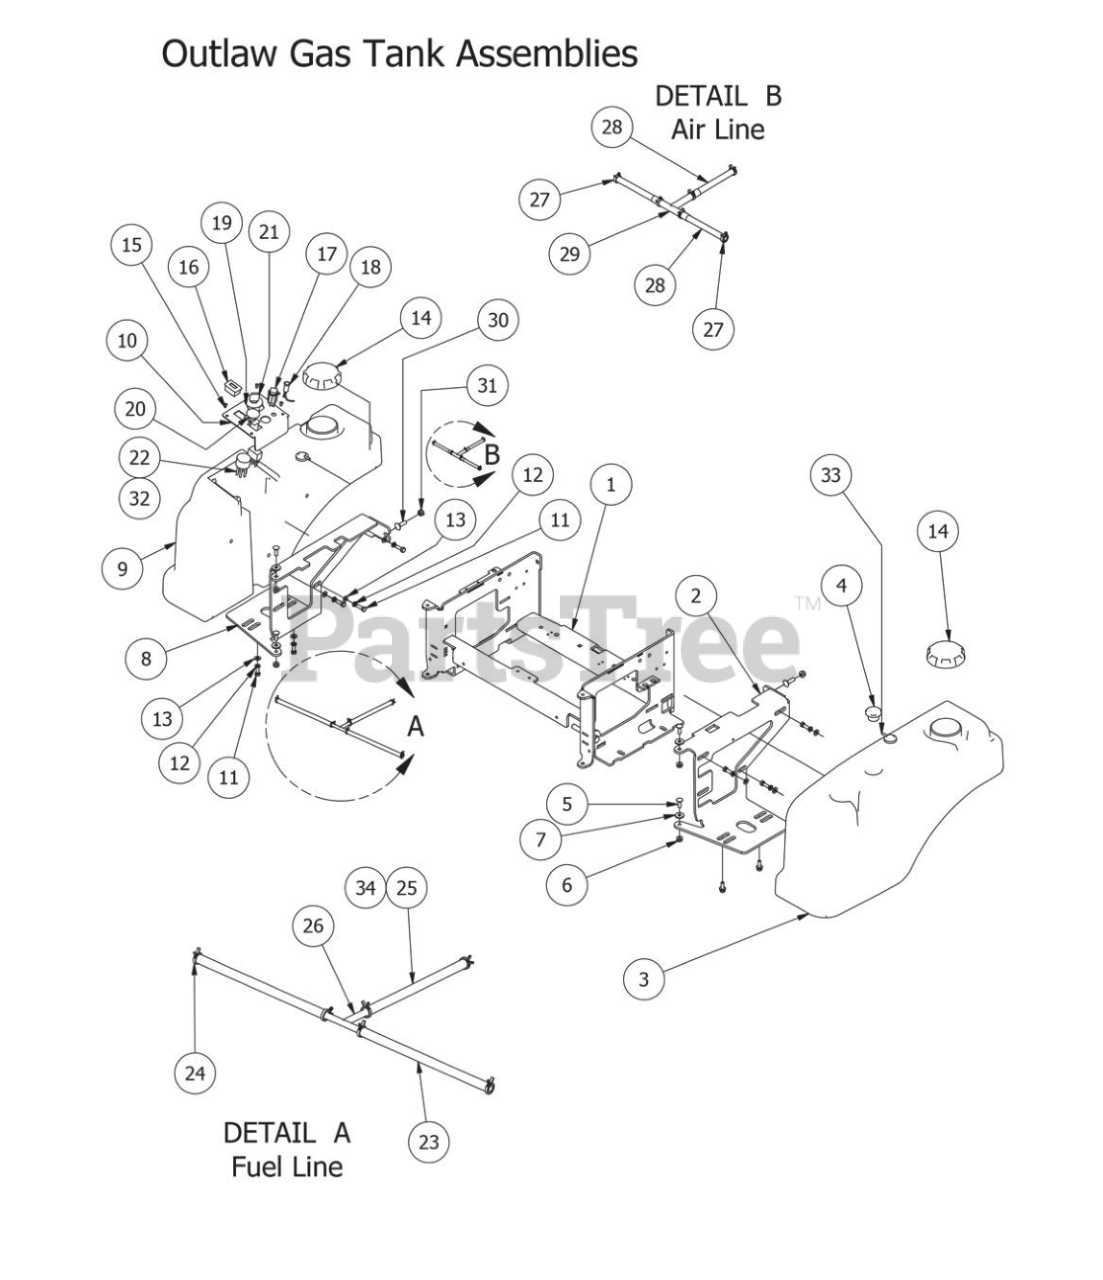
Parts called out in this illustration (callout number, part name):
1	Outlaw Seat Bracket 2012
2	Tank Support 2012 Outlaw (Left)
3	Left Fuel Tank/Outlaw/2012/EPA
4	Fuel Gauge and Grommet
5	5/16" x 1" Carriage Bolt
6	5/16-18 Nylon Flange Nut
7	.360 ID Plastic Washer
8	Outlaw Tank Support 2012 (Right)
9	Right Fuel Tank/Outlaw/2012/EPA
10	Outlaw Instrument Panel 2010
11	5/16" x 1" Bolt
12	5/16" Lock Washer
13	5/16" Flat Washer
14	3.5" Tethered Fuel Cap
15	10-32 x 3/8" Button Socket Head Bolt
16	Tachometer
17	12V AUX Connection
19	Ignition Switch
20	PTO Engager
21	Ignition Key
22	Wiring Harness 810 Briggs, 726 Ka, 747 Ko,
23	Fuel Line Assembly 726 Ka
24	1/4 fuel clamp
25	1/4" fuel line hose
26	fuel line T
27	3/16 vinyl clamp
28	1/4" vinyl tubing
29	fuel line T
30	3/8" x 1 1/4" Carriage Bolt
31	3/8" Nylock Flange Nut
32	Wiring Harness 29 EFI Kohler
33	Rollover Valve-White
34	Fuel line Assembly 29 EFI, 810 Briggs, 747 Ko
